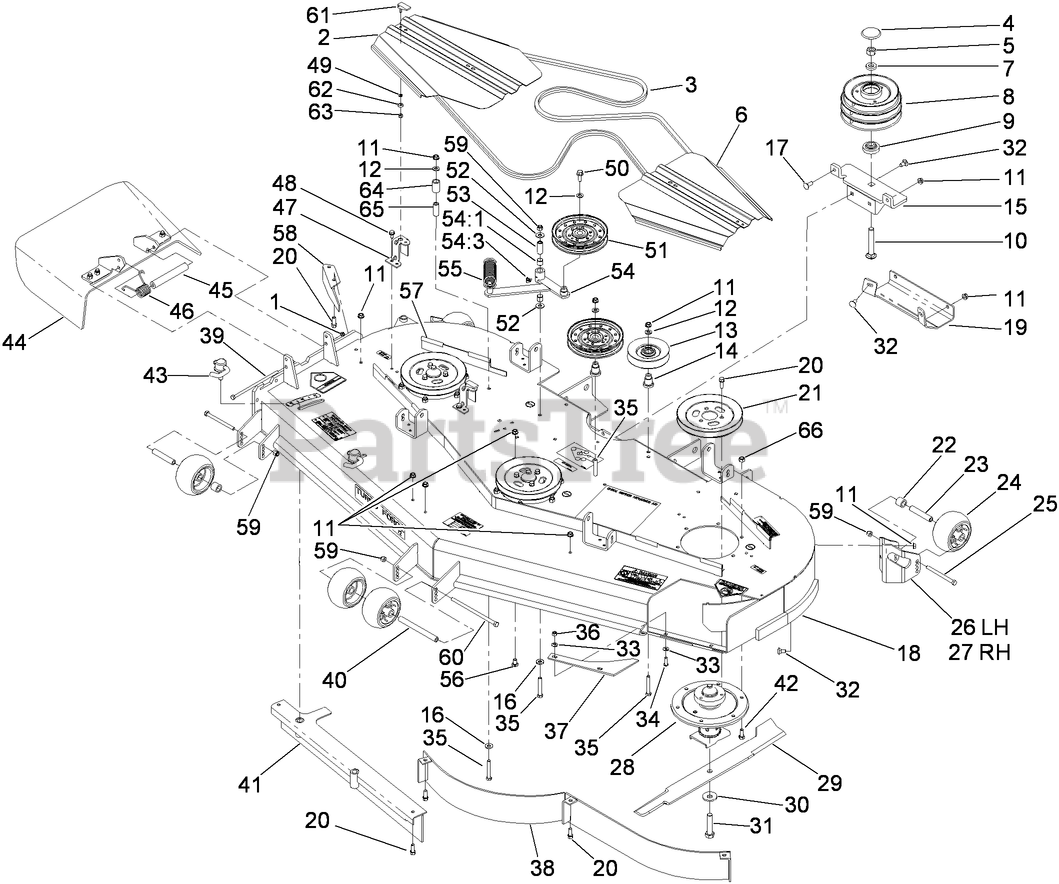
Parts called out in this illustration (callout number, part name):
1	NUT-LOCK, NI
2	COVER-BELT
3	BELT-V
4	CAP-PLASTIC
5	NUT-HEX
6	COVER-BELT
7	SPACER
8	PULLEY AND BEARING ASM
9	SPACER-FLANGED
10	BOLT-CARRIAGE
11	NUT-HHF, WHIZ
12	WASHER-FLAT
13	PULLEY-IDLER
14	MOUNT-PULLEY
15	MOUNTING BRACKET ASM
16	WASHER-BELLEVILLE
17	BOLT-CARR
18	DECK DECAL ASM
19	Plate-Skid
20	SCREW-HWH
21	PULLEY
22	TUBE-SPACER
23	TUBE-SPANNER
24	ROLLER-SCALP, ANTI
25	SCREW-HH
26	MOUNT-WHEEL, LH
27	MOUNT-WHEEL, RH
28	SPINDLE ASM
29	BLADE-HI FLOW, 24.5 INCH
30	Washer-Blade Bolt, Heavy
31	Screw-Cap
32	SCREW-CARR
33	WASHER-SPRING
34	SCREW-HSBH
35	SCREW-HH
36	NUT-LOCK, NI
37	PLATE-TURBO
39	SCREW-HH
40	SPACER-WHEEL
42	SCREW-HH
43	LEVER ASM
44	RUBBER DEFLECTOR ASM
45	SPACER
46	SPRING-TORSION
47	BRACKET-COVER
48	SCREW-HWHTF
49	WASHER
50	SCREW-HHF
51	Idler-Flat
52	WASHER-FLAT
53	BUSHING
54	IDLER ARM ASM
54:1	SLEEVE-BEARING
54:3	FITTING-GREASE, 90 DEG
55	SPRING-EXTENSION
56	SCREW-CARR
57	STRIP-SEAL
58	BAFFLE-DISCHARGE
59	NUT-LOCK, NI
60	SCREW-HH
61	HANDLE-LATCH, SWELL
62	BUSHING-LATCH, SWELL
63	NUT-LOCK, HH
64	SPACER-RUBBER
65	SPACER-PIVOT, IDLER
66	NUT-LOCK, NI
